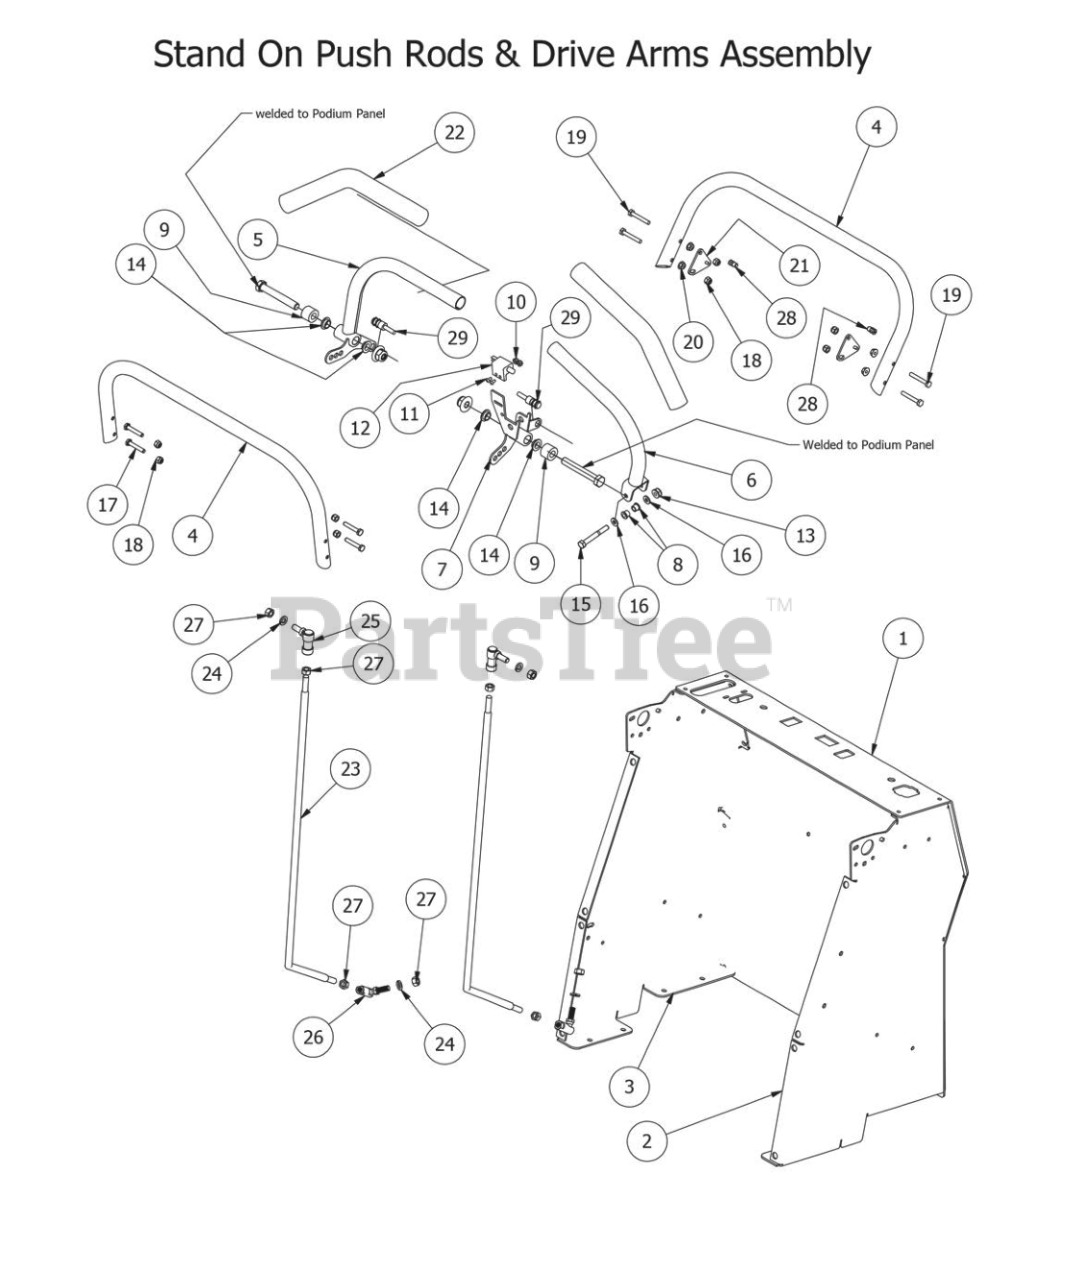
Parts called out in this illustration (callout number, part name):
1	Podium Front Panel
2	Podium Panel Right Side
3	Podium Panel Left Side
4	Support Handle Stand Up (Front & Back)
5	Left Steering Handle Assembly
6	Right Steering Handle Assembly
7	Safety Kill Switch Assembly Bracket
8	Stand On Flange Bushing-Steering Arms
9	Steering Arm Spacer- Stand On
10	10-24 Nylon Insert Locknut
11	1024 X 5/8" Buttonhead Bolt
12	Safety Switch
13	5/16-18 Nylon Flange Nut
14	Bushing for 2012 Drive Arms
15	5/16" x 2 1/2" Bolt
16	1/4" Flat Washer
17	1/4-20 x 1 1/2" Bolt
18	1/4" Nylock Nut
19	1/4-20x 1-3/4" Hex Bolt
20	1/4-20 Hex Flange Nuts Zinc w/Serrations
21	Neutral Safety Tab
22	Black Steering Grip
23	Push Rod Stand
24	3/8" Lock Washer
25	3/8-24 Quick Release Ball Joint
26	3/8-24 Ball Joint
27	3/8" Fine Threaded Jam Nut
28	Magnet-Steering Arm-Stand On
29	Safety Switch Harness
30	1/2-13 Nylon Flange Nut-Orange
